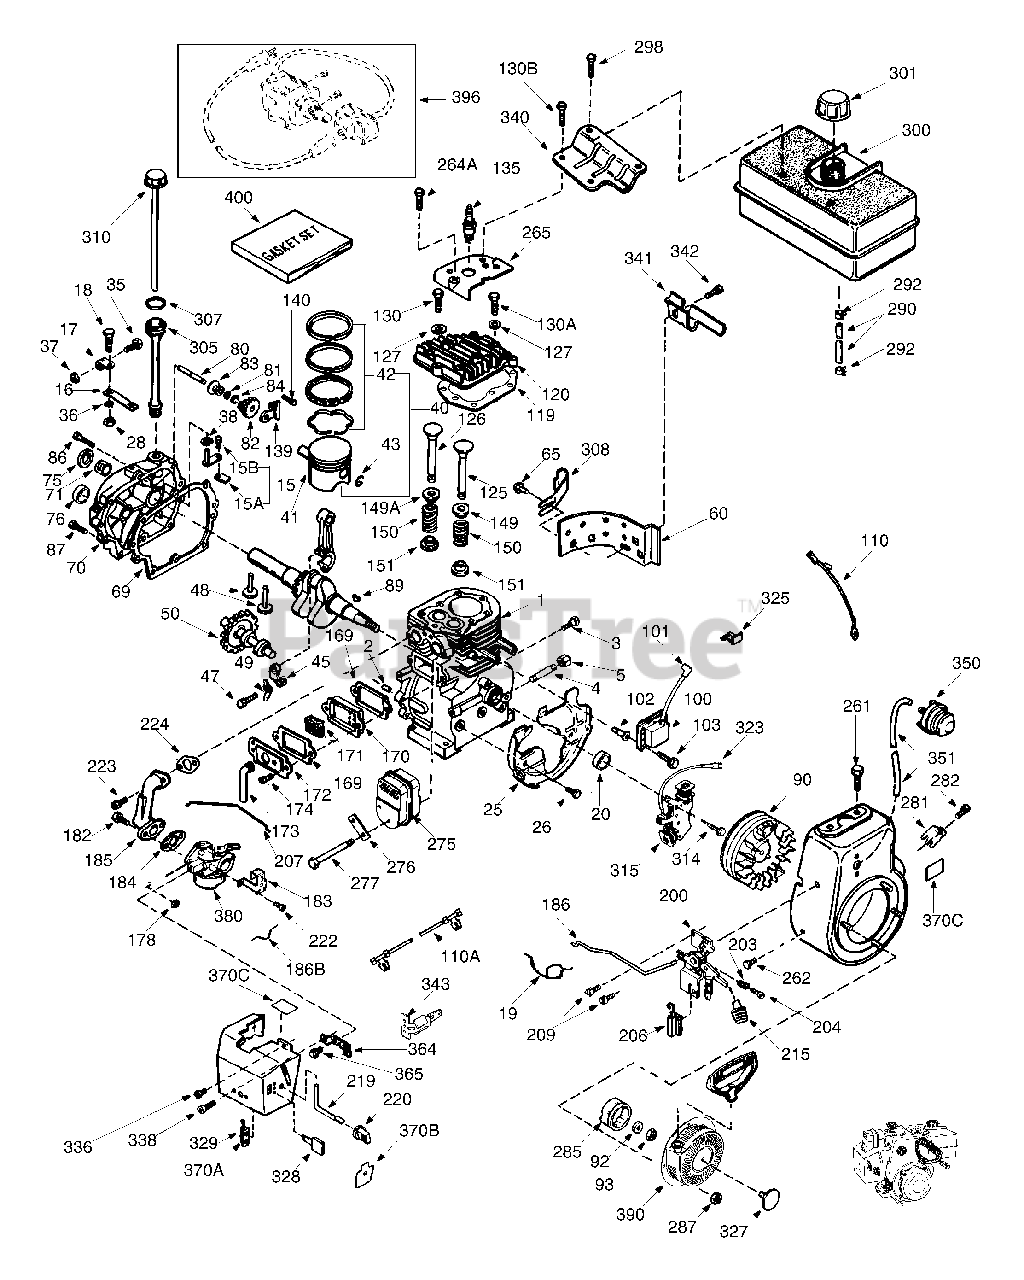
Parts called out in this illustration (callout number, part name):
1	Cylinder
2	Dowel Pin
4	Oil Drain Extension
5	Extension Cap
15	Governor Rod
15A	Governor Yoke
16	Governor Lever
17	Governor Lever Clamp
18	Screw, Torx
19	Speed Control Spring
20	Oil Seal
25	Blower Housing Baffle
28	Lock Nut
36	Lock Washer
37	Lock Nut
38	Retaining Ring
40	Piston, Pin & Ring Set (Std.)
40	Piston, Pin & Ring Set (.010" OS)
41	Piston, & Pin Ass'y. (Std.)
41	Piston, & Pin Ass'y. (.010" OS)
42	Ring Set (Std.)
42	Ring Set (.010" OS)
43	Piston Pin Retaining Ring
45	Connecting Rod Ass'y.
47	Connecting Rod Bolt
48	Valve Lifter
49	Oil Dipper
50	Camshaft (MCR)
60	Blower Housing Extension
69	Cylinder Cover Gasket
70	Cylinder Cover
71	Crankshaft Bushing
75	Oil seal
76	Camshaft Seal
80	Governor Shaft
82	Governor Gear Ass'y.
83	Governor Spool
84	Retaining Ring
89	Flywheel Key
90	Flywheel (W/ Ring Gear)
92	Belleville Washer
93	Flywheel Nut
100	Solid State Ignition
101	Spark Plug Cover
102	Solid State Mounting Stud
103	Screw, Torx
110	Ground Wire
110A	Ground Wire
119	Cylinder Head Gasket
120	Cylinder Head
125	Exhaust Valve (Std.)
125	Exhaust Valve (1/32" Os)
126	Intake Valve(Std.)
126	Intake Valve (1/32" Os)
130B	Screw
135	Resistor Spark Plug
139	Governor Gear Bracket
140	Screw
149	Valve Spring Cap
149A	Valve Spring Cap
150	Valve Spring
151	Valve Spring Keeper
169	Valve Cover Gasket
170	Breather Body
171	Breather Element
172	Valve Cover
173	Breather Tube
178	Nut & Lock Washer
183	Choke Bracket
184	Carburetor to intake pipe gasket
185	Intake Pipe
186	Governor Link
186B	Choke Spring
200	Control Bracket
203	Compression Spring
204	Torx. Screw
206	Terminal
207	Throttle Link
215	Control Knob
219	Choke Rod
220	Choke Knob
222	Screw
223	Screw, Torx
224	Intake Pipe Gasket
262	Screw, Torx
265	Cylinder Head Cover
275	Muffler
276	Locking Plate
281	Starter Bubble Cover
285	Starter Cup
287	Nut & Lock Washer
290	Fuel Line
292	Fuel Line Clamp
300	Fuel Tank
301	Fuel Cap
305	Oil Fill Tube
307	"O" Ring
308	Fill Tube Clip
310	Dipstick
315	Alternator Coil
325	Wire Clip
327	Starter Plug
328	Ignition Key
329	Terminal
340	Fuel Tank Bracket
341	Fuel Tank Bracket
343	Key Switch Bracket
350	Primer Bulb
351	Primer Line
364	Carburetor Cover Bracket
370A	Primer Decal
370B	Choke Decal
370C	Warning Decal
380	Carburetor
390	Rewind Starter
396	Electric Starter Motor
400	Gasket Set
